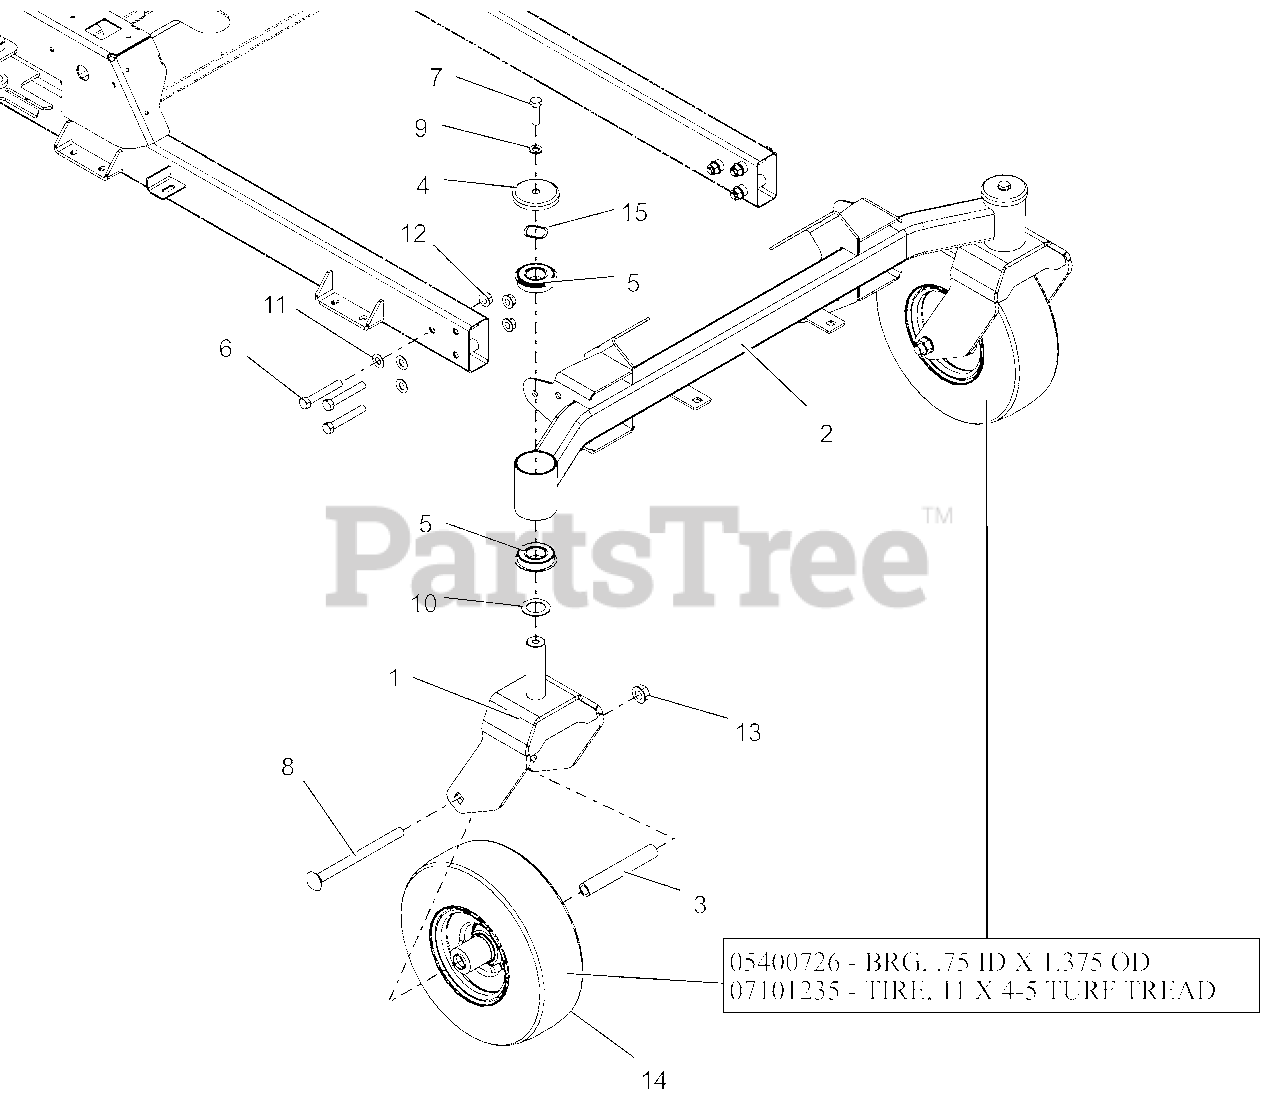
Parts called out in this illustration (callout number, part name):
1	WLDMT, CASTER FORK-X (RED)
2	WLDMT, FRONT AXLE-X/XL (RED)
3	SPACER, ROLLED WHEEL
4	SHIELD, AXLE BEARING
5	BEARING, BALL -2.000 OD X 1.000 ID X .5625 W/RING
6	BLT, HEX .38-16X2.50 G8 ZCC
7	BLT, HEX .38-16X1.25 G5 ZCC
8	BLT, RHSN .50-13X6.50 G5 ZCC
9	WSHR,LK-REG .375X.094 ZCC
10	WSHR-HRD-THRS 1.007X1.542X.062
11	WSHR-FL-STL 0.406X0.812X0.055 HRD
12	NUT-LK-TOP-FLG .375-16 GG ZCC
13	NUT-LK-TOP-FLG .500-13 GF ZCC
14	ASM, WHL/TIRE 11X4.00-5
14	BRG, .75 ID X 1.375 OD
14	TIRE, 11X4-5 TURF TREAD
14	TUBE 11 X4.0-5 TR87
15	WSHR-WAVE 1.0X1.25X.028 .145FH
